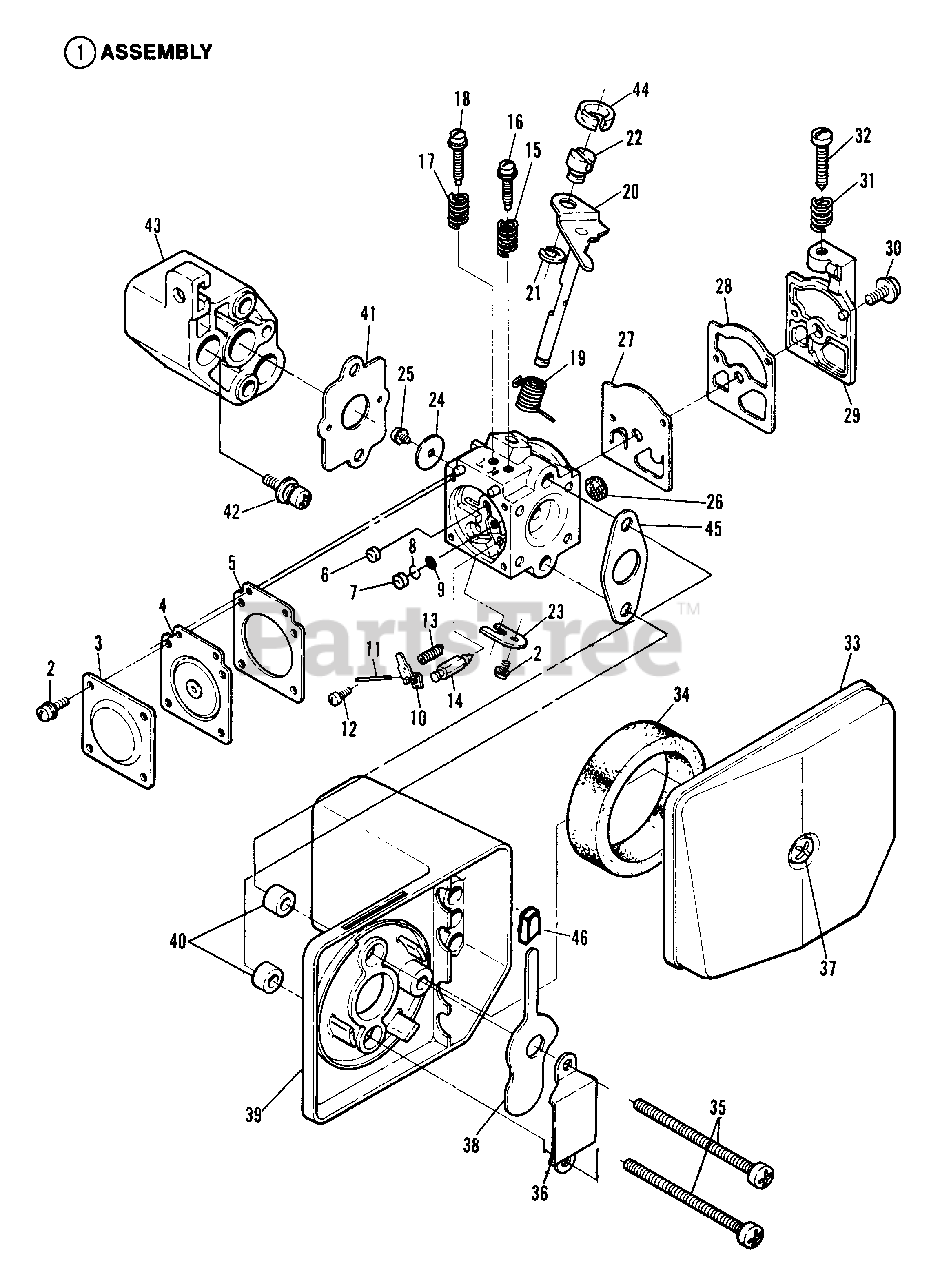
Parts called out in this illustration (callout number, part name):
1	CARBURETOR ASS'Y.
2	SCREW, Cover
3	COVER, Diaphragm
4	DIAPHRAGM, Metering
5	GASKET, Diaphragm
6	PLUG, Welch
7	PLUG, Welch
8	RING, Screen Retainer
9	SCREEN, Check Valve
10	LEVER, Metering
11	PIN, Lever
12	SCREW, Lever Pin
13	SPRING, Lever
14	VALVE, Inlet Needle
15	SPRING, High Speed Needle
16	NEEDLE, High Speed
17	SPRING, Idle Needle
18	NEEDLE,Idle
19	SPRING, Throttle Return
20	SHAFT, Throttle
23	CLIP, Throttle Shaft
24	VALVE, Throttle
25	SCREW, Throttle
26	SCREEN, Inlet
27	DIAPHRAGM, Fuel Pump
28	GASKET, Fuel Pump
29	COVER, Fuel Pump
30	SCREW, Pump Cover
31	SPRING, Idle Screw
32	SCREW, Idle Adjusting
33	COVER, Air Cleaner
34	FILTER, Air Cleaner
35	SCREW, Carburetor Mounting
37	SCREW & WASHER
38	LEVER, Choke
40	SLEEVE, Choke Base
41	GASKET, Carburetor
42	SCREW, Insulator Mounting
43	INSULATOR, Carburetor
45	GASKET, Choke Base Mounting
46	COVER, Choke Lever
